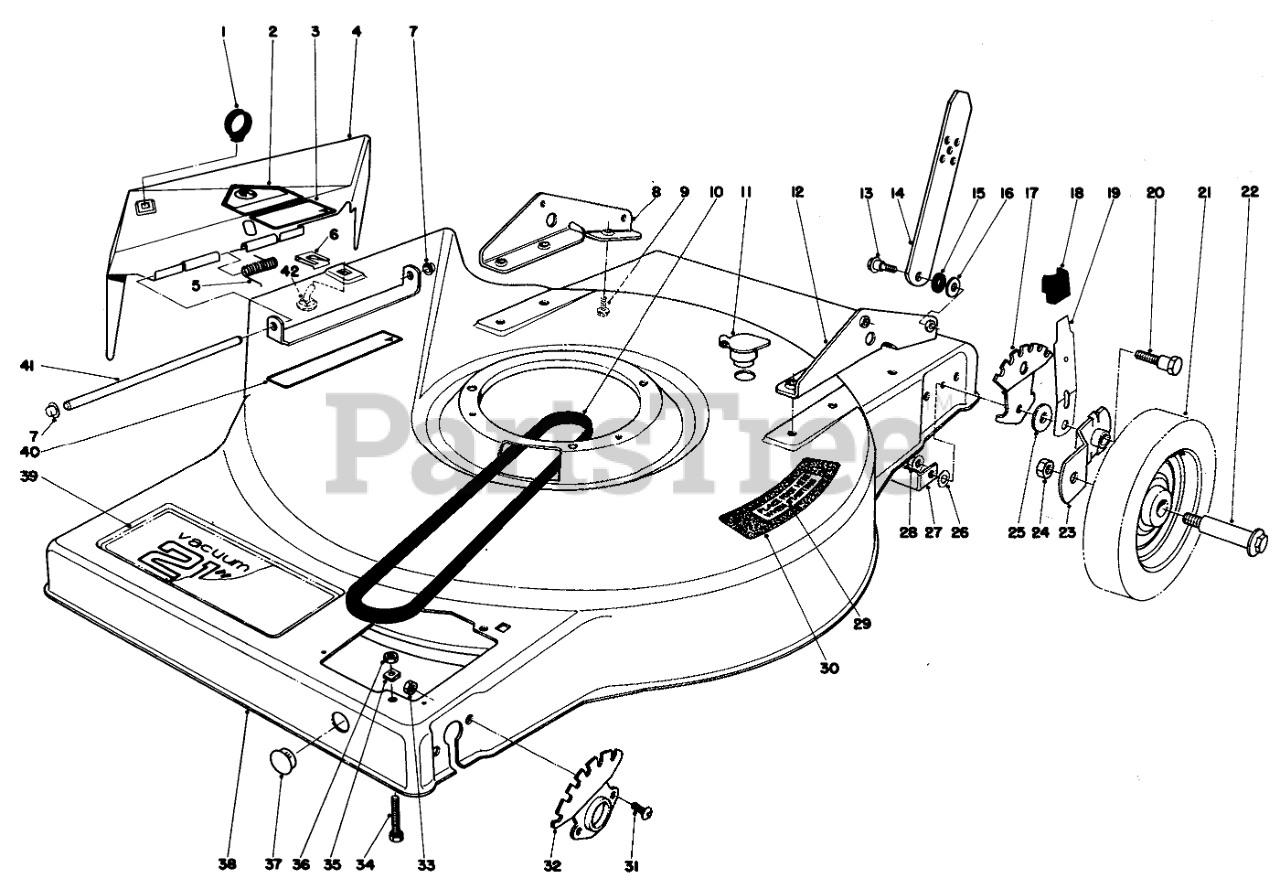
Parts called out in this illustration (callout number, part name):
1	LIFT LOOP
2	DECAL-DANGER
3	DECAL DEFLECTOR
4	DefIector
5	TORSION SPRING
6	BAG CHUTE CLIP PIN
7	PUSHNUT-CAP, WASHER
8	Bracket Handle R.H.
9	SCREW-HWHTF
10	V-BELT
11	WASHOUT PLUG
12	Bracket-L.H.
13	SCREW-SHOULDER
14	Handle Latch
15	SPACER
16	WASHER-PLAIN
17	Quadrant
18	KNOB-ARM
19	SPRING ARM ASM
20	PIVOT SCREW
21	Wheel Assembly
23	PIVOT ARM ASM A
24	Nut
25	PIVOT WASHER
26	WASHER
27	DECK SUPPORT
29	Decal Step Pad
30	PAD STEP
31	Capscrew-Button Head
32	QUADRANT S.P.
33	NUT-LOCK, CONE
34	SCREW
35	SPEED NUT
36	NUT-JAM
37	Hole Plug
38	Housing
39	Decal-Deck
40	DECAL CAUTION
41	DEFLECTOR PIVOT ROD
42	BAG CHUTE PIN
